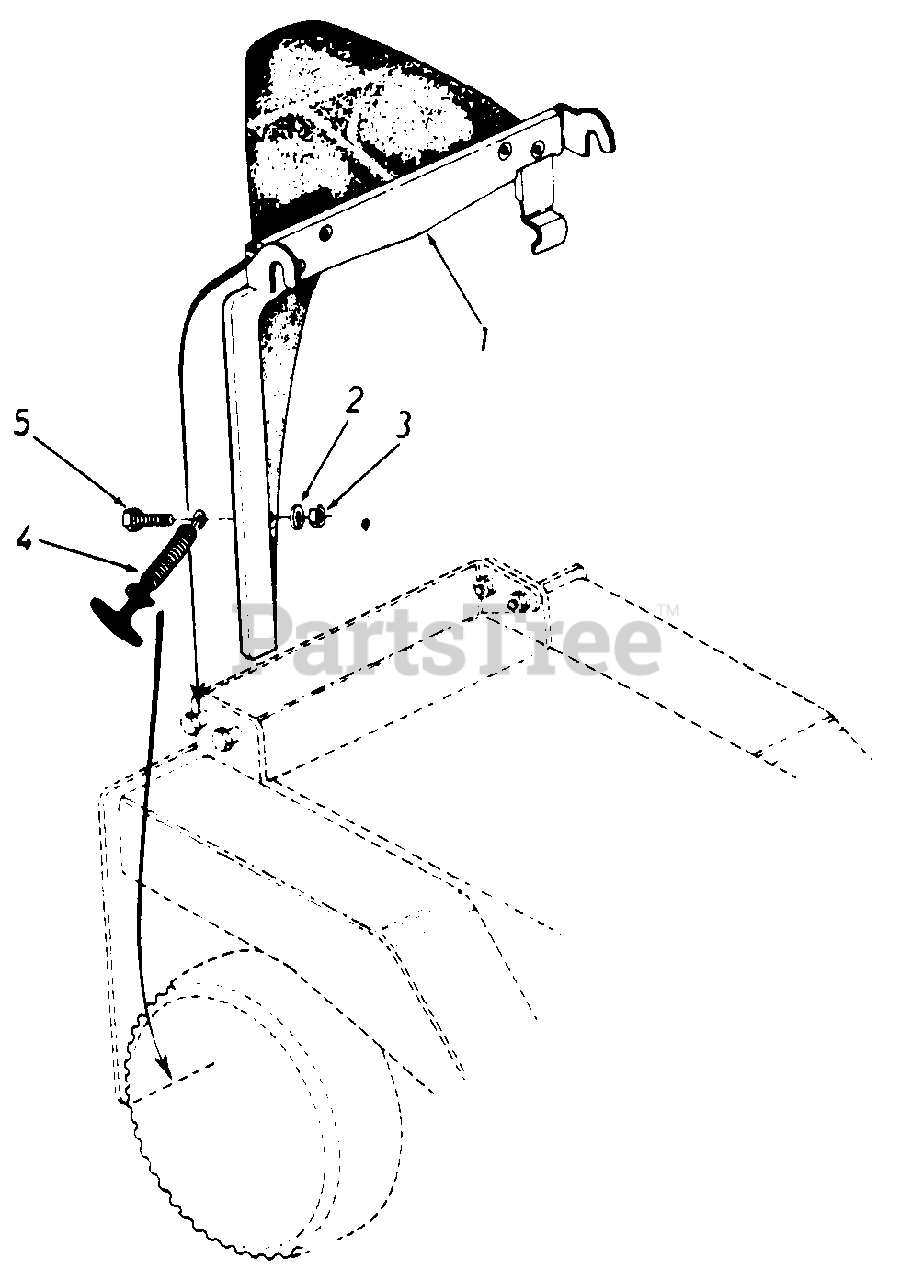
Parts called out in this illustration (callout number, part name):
1	Grass Deflector Ass'y.
2	L.-Wash. 1/4" Scr.
3	Hex Nut 1/4-20 Thd.
4	Hood Lock Ass'y.
5	Hex Scr. 1/4-20 x .62" Lg.
